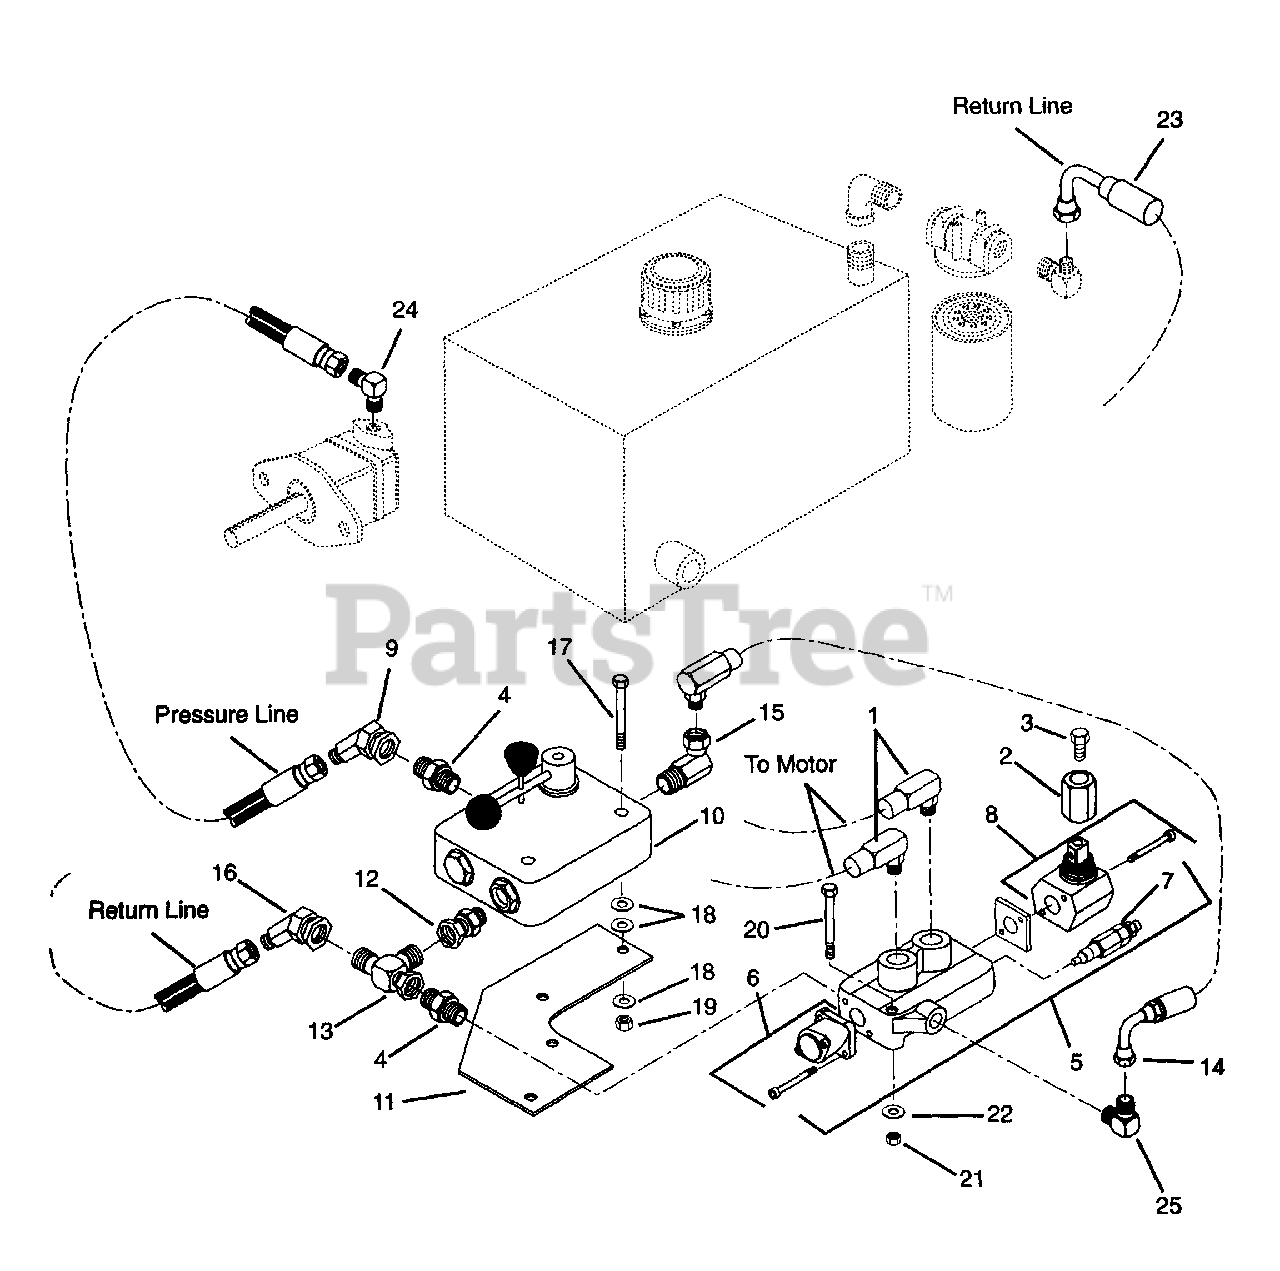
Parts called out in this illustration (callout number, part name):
1	Hydraulic Hose
2	Hex Adapter
3	Screw M8 x 1.25 x 20MM
4	Adapter, Hydraulic Steel 3/4 inch "O" Ring to 3/4 NPT
5	Valve, Hydraulic
6	Detent Assembly-Hydraulic Control Valve
7	Relief Valve
8	Lever Assembly
9	45 Degree NPTF Elbow
10	Flow Control Valve-Hydraulic
11	Bracket-Manual Feed
12	Straight Swivel Fitting
13	Swivel Tee
14	Hose - 3500 psi Hydraulic .50 x 17.88
15	90 Degree Swivel Adapter
16	Swivel Elbow - 45 Degree
17	Bolt-Hex .31-18 x 2.50-Grade 5
18	Washer-Flat-Steel .31 x .734 x .065
19	Nut-Locking-Center .31-18
20	Bolt-Hex .25-20 x 2.50-Grade 5
21	Nut-Lock-Center .25-20
22	Washer-Flat-Steel .312 x .734 x .049
23	Hydraulic Hose
24	Adapter-Hydraulic Elbow 3/4 Inch "O" Ring to 3/4 NPT
25	Fitting, Hydraulic
